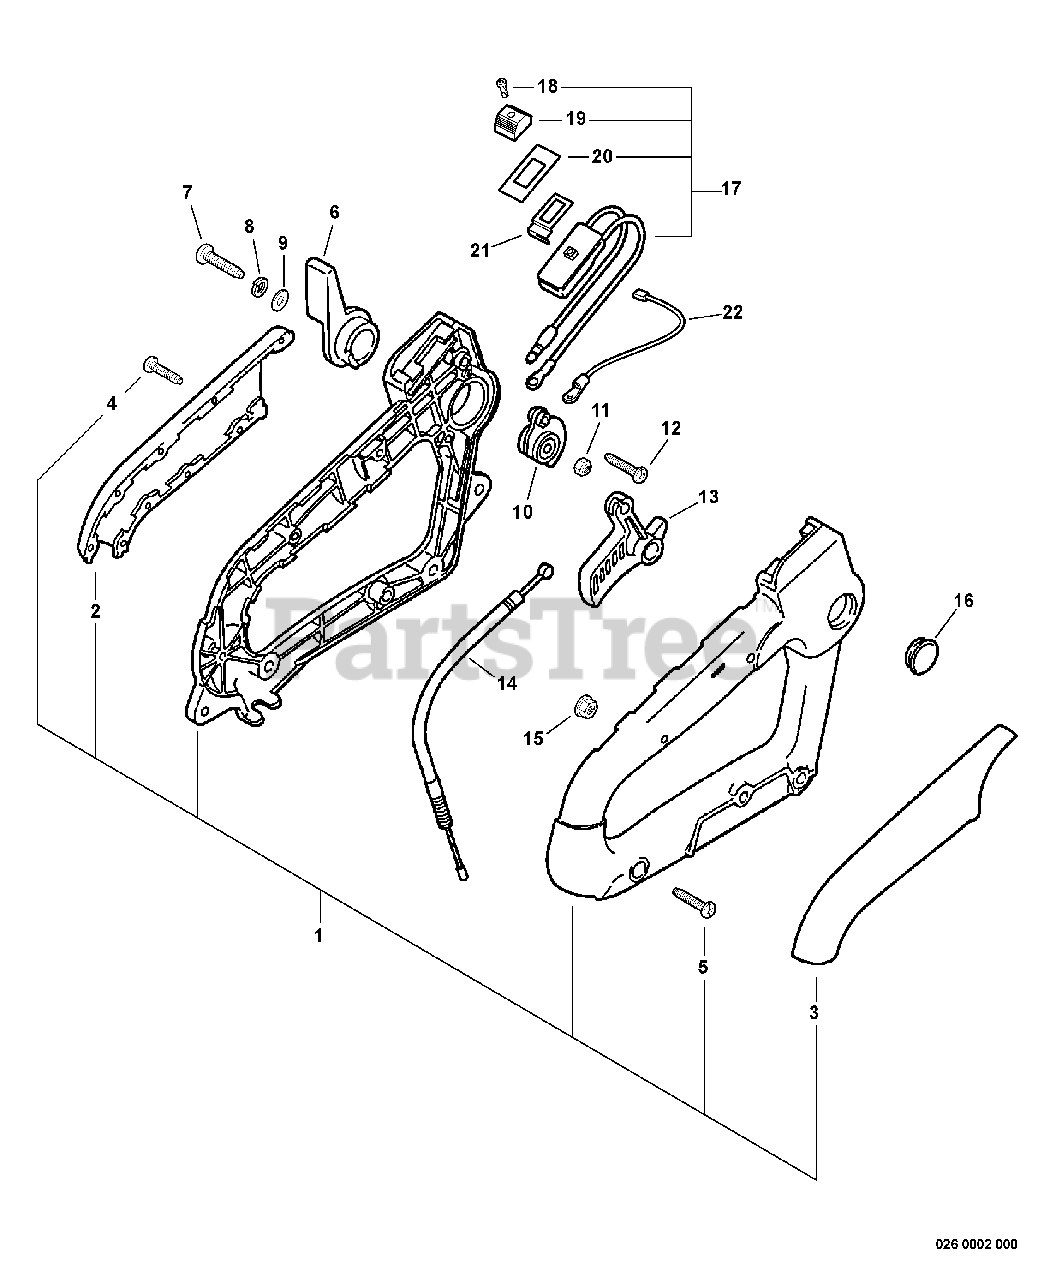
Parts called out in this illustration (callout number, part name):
1	HANDLE KIT
2	GRIP, LEFT
3	GRIP, RIGHT
4	SCREW 4×22
5	SCREW 5×30
6	CONTROL, THROTTLE
7	SCREW 6×20
8	WASHER, SPRING 6
9	WASHER 6.5×13×1
10	BRACKET, THROTTLE
12	SCREW 4×10
13	TRIGGER, THROTTLE
14	CABLE, THROTTLE
15	NUT, FLANGE M5
17	SWITCH, ON-OFF
18	SCREW 3×10
19	KNOB, SWITCH - ORANGE
20	LABEL, SWITCH
21	TERMINAL
